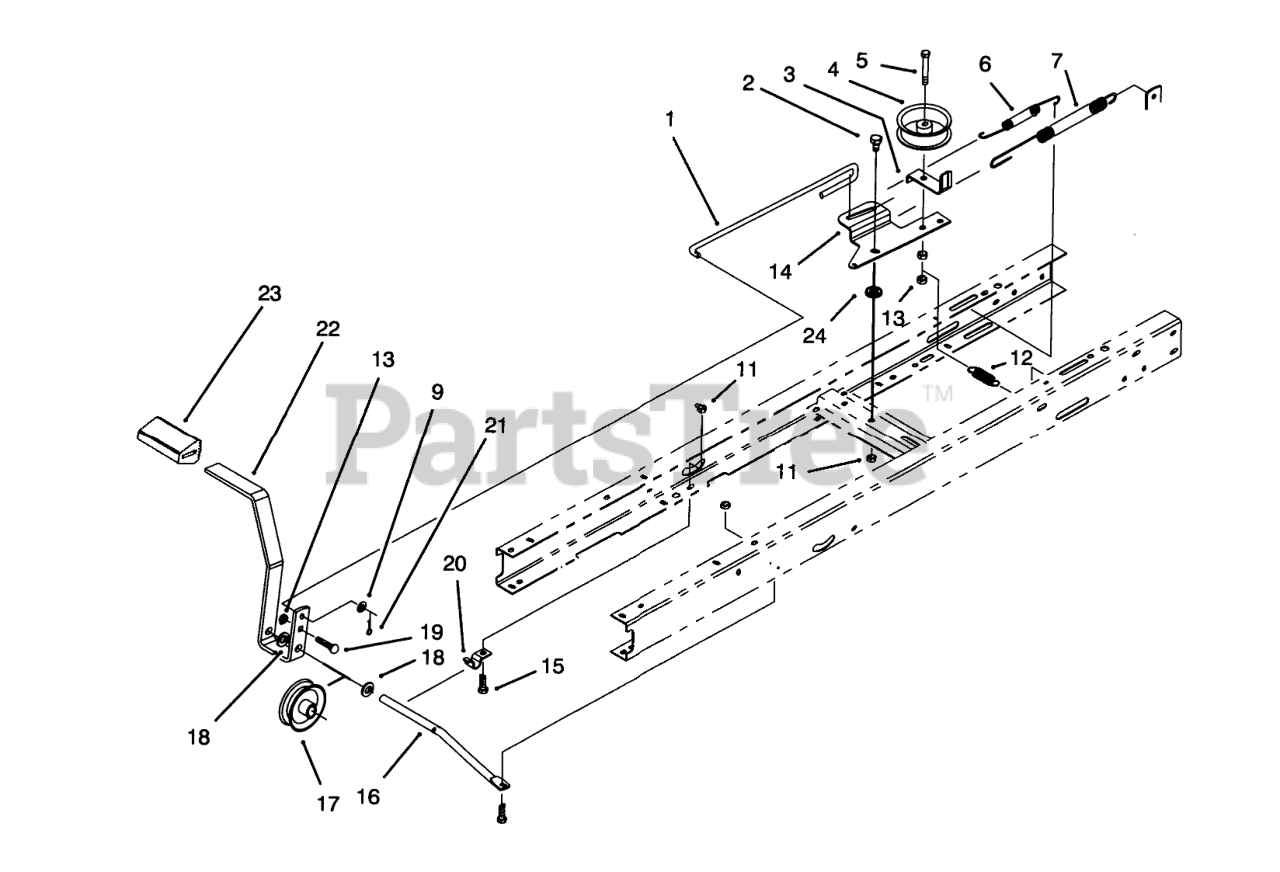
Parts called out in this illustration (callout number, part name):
1	ROD-CLUTCH/BRAKE
2	BOLT-SHOULDER
3	GUIDE-IDLER, BELT
4	Idler Pulley
5	SCREW-HH
6	SPRING-EXTENSION
7	BRAKE SPRING
9	WASHER-PLAIN
11	NUT-LOCK, NI
12	SPRING-EXTENSION
13	NUT-LOCK, NI
14	ARM-IDLER
15	SCREW-HH
16	ROD-PIVOT, PEDAL
17	PULLEY, CABLE
18	WASHER-FLAT
19	SCREW-CARR
20	CLAMP-PIVOT, SHIFT
21	PIN-COTTER
22	Pedal-Clutch/Brake
23	PAD-PEDAL
24	WASHER-PIVOT
